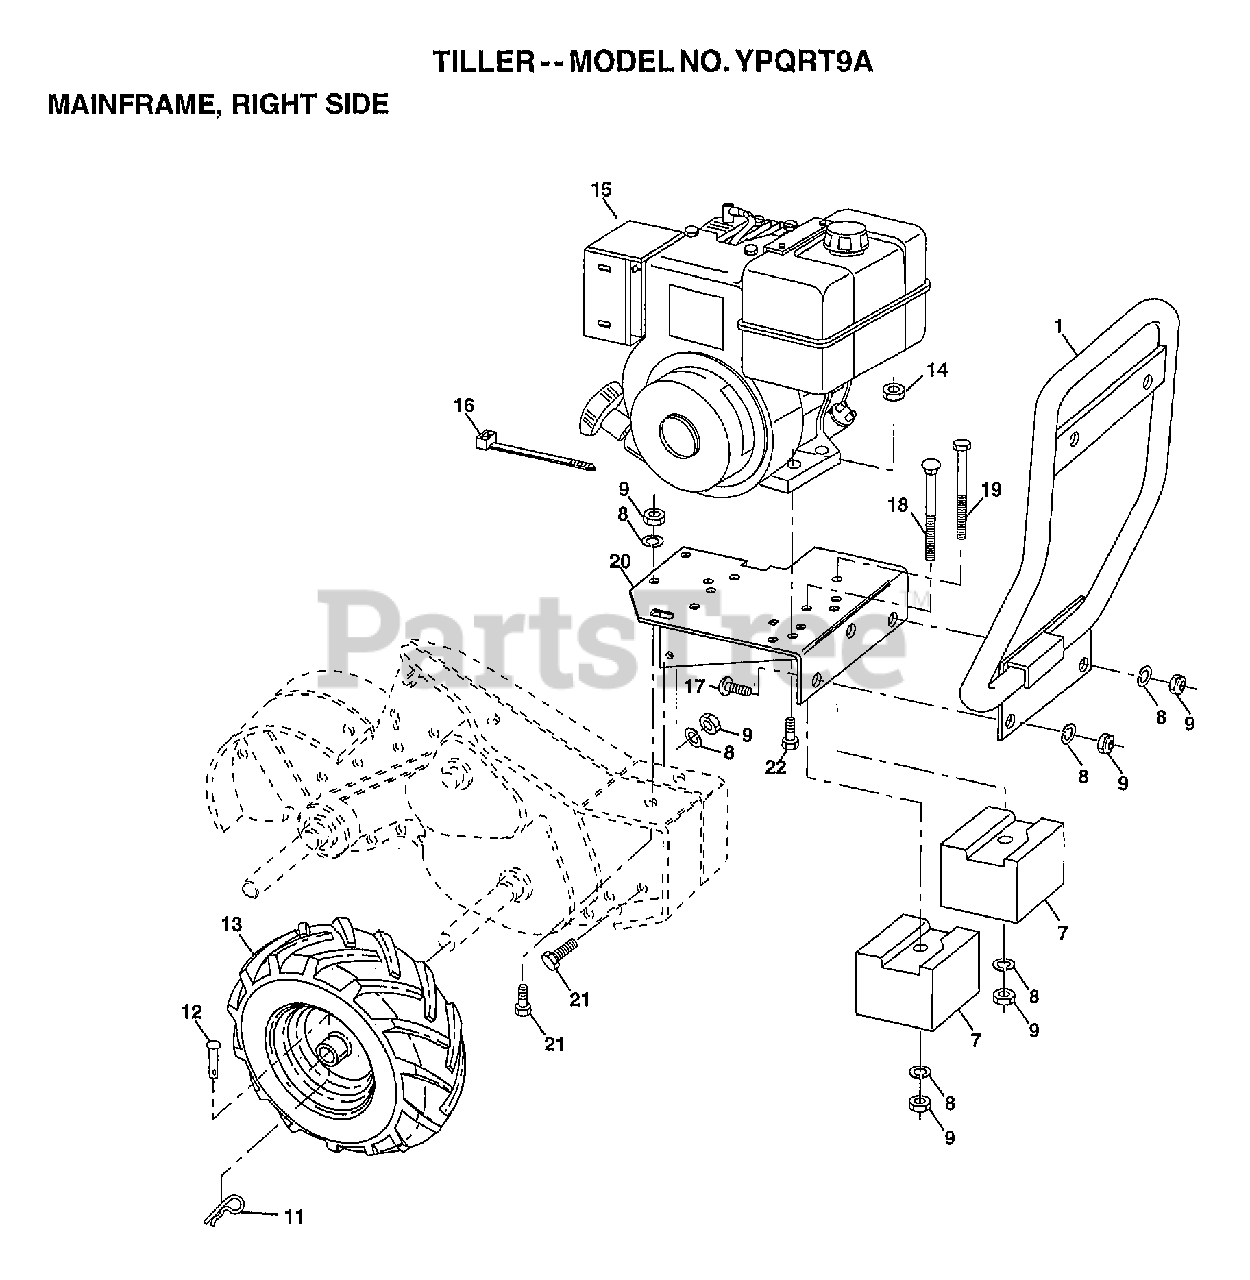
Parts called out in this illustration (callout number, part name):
1	BUMPER.ASM
7	COUNTERWEIGHT CRT
8	LOCKWASHER
9	NUT.HEX.3/8-16UNC
11	SPRING.RETAINER
12	RIVET.PAN HD.1.75
13	TIRE TI
13	RIM.16X4X8.WHT
16	WIRE TIE
18	BOLT CRT
19	BOLT.3/8-16X4.5
20	"ASM. ENGINE, BASE"
21	BOLT
22	BOLT
